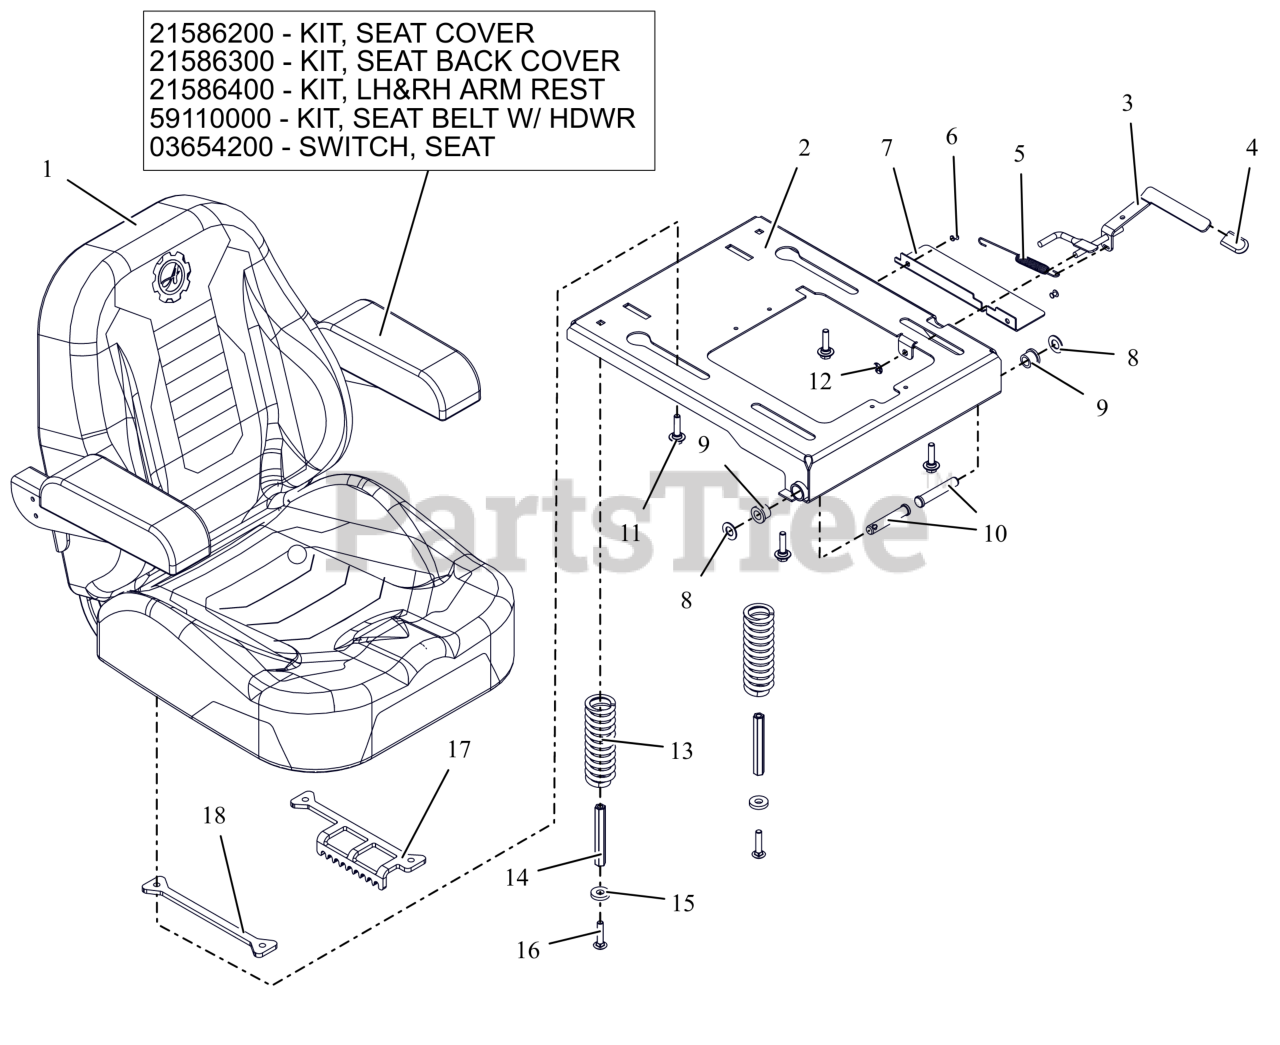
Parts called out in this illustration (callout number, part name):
1	SEAT- APEX/ZENITH
1	KIT, SEAT COVER BOTTOM
1	KIT, SEAT BACK COVER
1	KIT, LH & RH ARM REST
1	KIT-SEAT BELT REPLACE-05007300
1	SWITCH- SEAT
2	WLDMT, SEAT PLATE HD
3	WLDMT, SEAT SLIDE LEVER
4	GRIP, SEAT LEVER, GREY
5	SG-TENS .06X.482X5.35
6	RIVET, .1875 AL/AL .126-.250
7	GUARD, SEAT PLATE
8	WSHR, FLT .531X1.00X.063 ZCC
9	BSHG, FLG .516X.750X.625X.937
10	PIN-CLIC .50X2.70X2.31 -ZCC
11	BOLT SHLDR .31-18 X .175
12	NUT-PUSH .312
13	SPRING, COMPRESSION SEAT 224LB
14	NUT, COUPLING 5/16X18 X 3.75
15	WSHR, FLT .406X1.00X.188 ZCC
16	BLT,RHSN .31-18X1.50 G5 ZCC
17	PLATE, SEAT ADJ (BLACK)
18	PLATE, ADJ SEAT SLIDE (BLACK)
